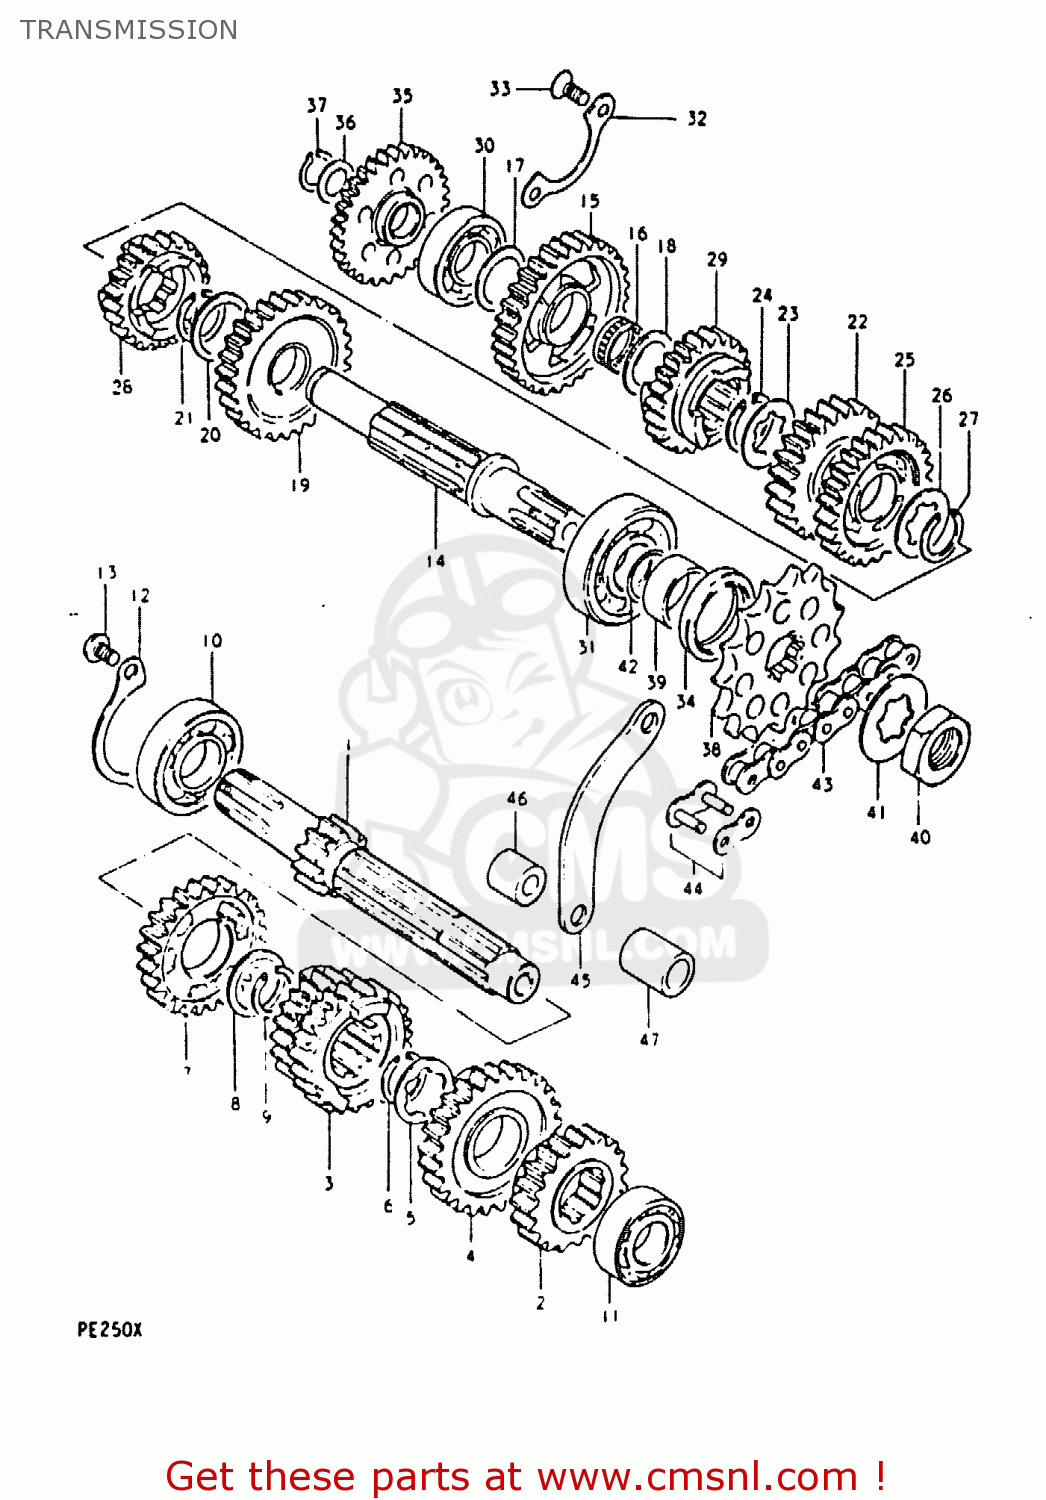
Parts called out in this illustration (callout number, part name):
1	SHAFT,COUNTER
2	GEAR,SECOND DRIVE
3	GEAR,THIRD/FOURTH DRIVE
4	GEAR,FIFTH DRIVE
5	WASHER,LOCK
6	CIRCLIP
7	GEAR,SIXTH DRIVE
8	SHIM(22X28X0.5)
9	CIRCLIP
10	BEARING
11	BEARING
12	PLATE,COUNTERSHAFT BEARING
13	SCREW 6X12
14	SHAFT,DRIVE
15	GEAR,FIRST DRIVEN
16	BEARING(17X21X9.8)
17	WASHER
18	WASHER,THRUST
19	GEAR,SECOND DRIVEN
20	SHIM(22X28X0.5)
21	CIRCLIP
22	GEAR,THIRD DRIVEN
23	WASHER,LOCK
24	CIRCLIP
25	GEAR,FOURTH DRIVEN
26	WASHER,LOCK
27	CIRCLIP
28	GEAR,FIFTH DRIVEN
29	GEAR,SIXTH DRIVEN
30	BEARING
31	BEARING
32	PLATE,DRIVESHAFT BEARING
33	SCREW
34	SEAL,OIL(32X42X6)
35	GEAR,KICK STARTER IDLE
36	CIRCLIP
37	WASHER
38	SPROCKET,ENGINE
39	SPACER(22X32X11.5)
40	NUT
41	WASHER,LOCK
42	O RING(D:1.7,ID:22)
43	CHAIN ASSEMBLY,DRIVE
44	JOINT ASSEMBLY,CHAIN
45	PLATE,FR CHAIN GUIDE
46	SPACER(8.6X16X24)
47	CUSHION
